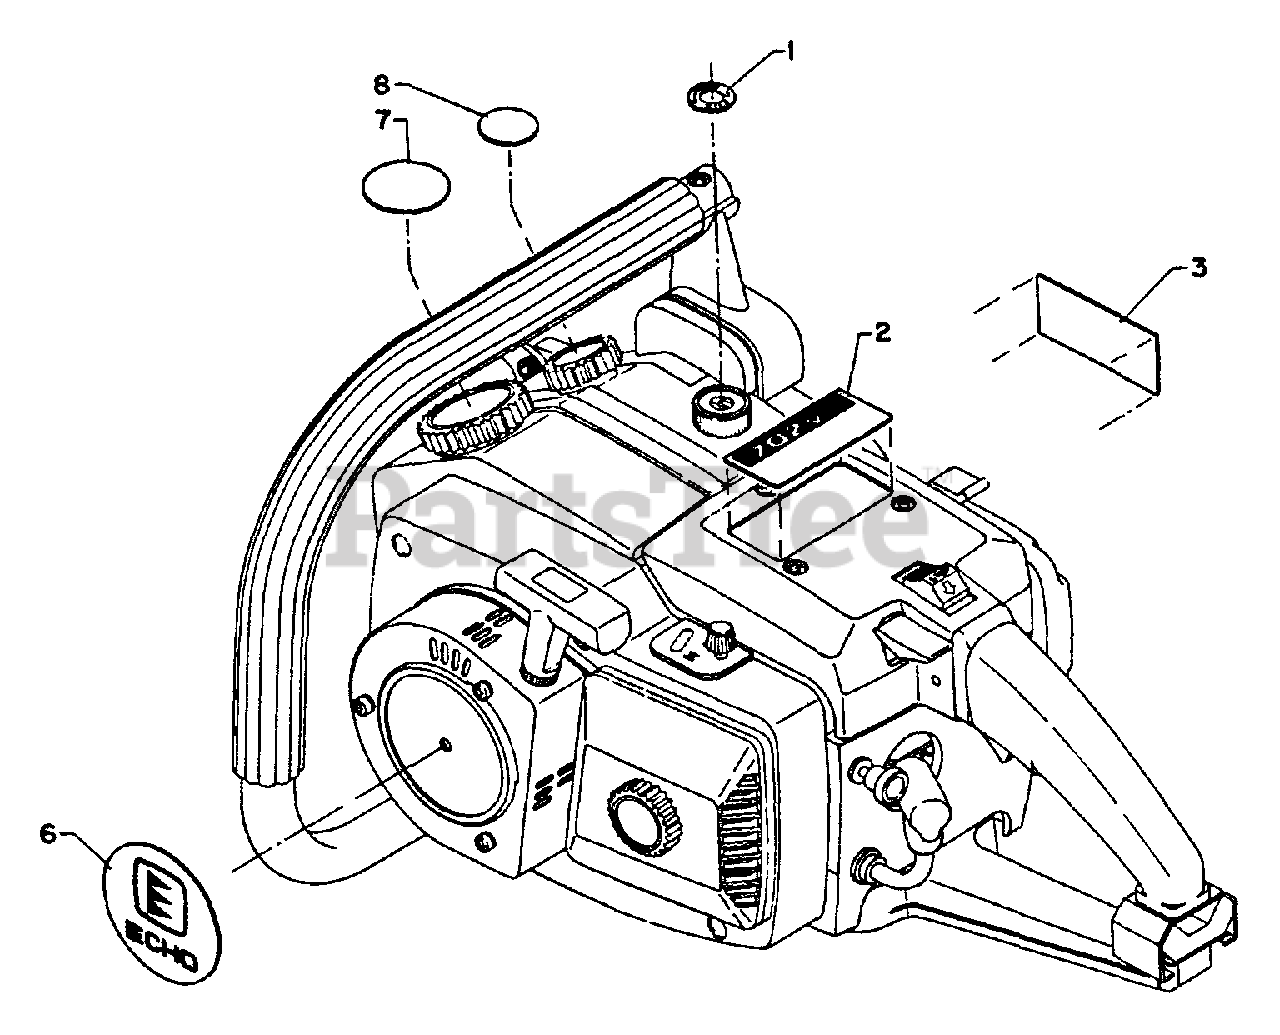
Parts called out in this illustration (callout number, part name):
1	LABEL, CAUTION
2	LABEL - CAUTION
3	LABEL - ECHO
6	LABEL
7	LABEL - FUEL MIX
8	LABEL - CHAIN OIL
